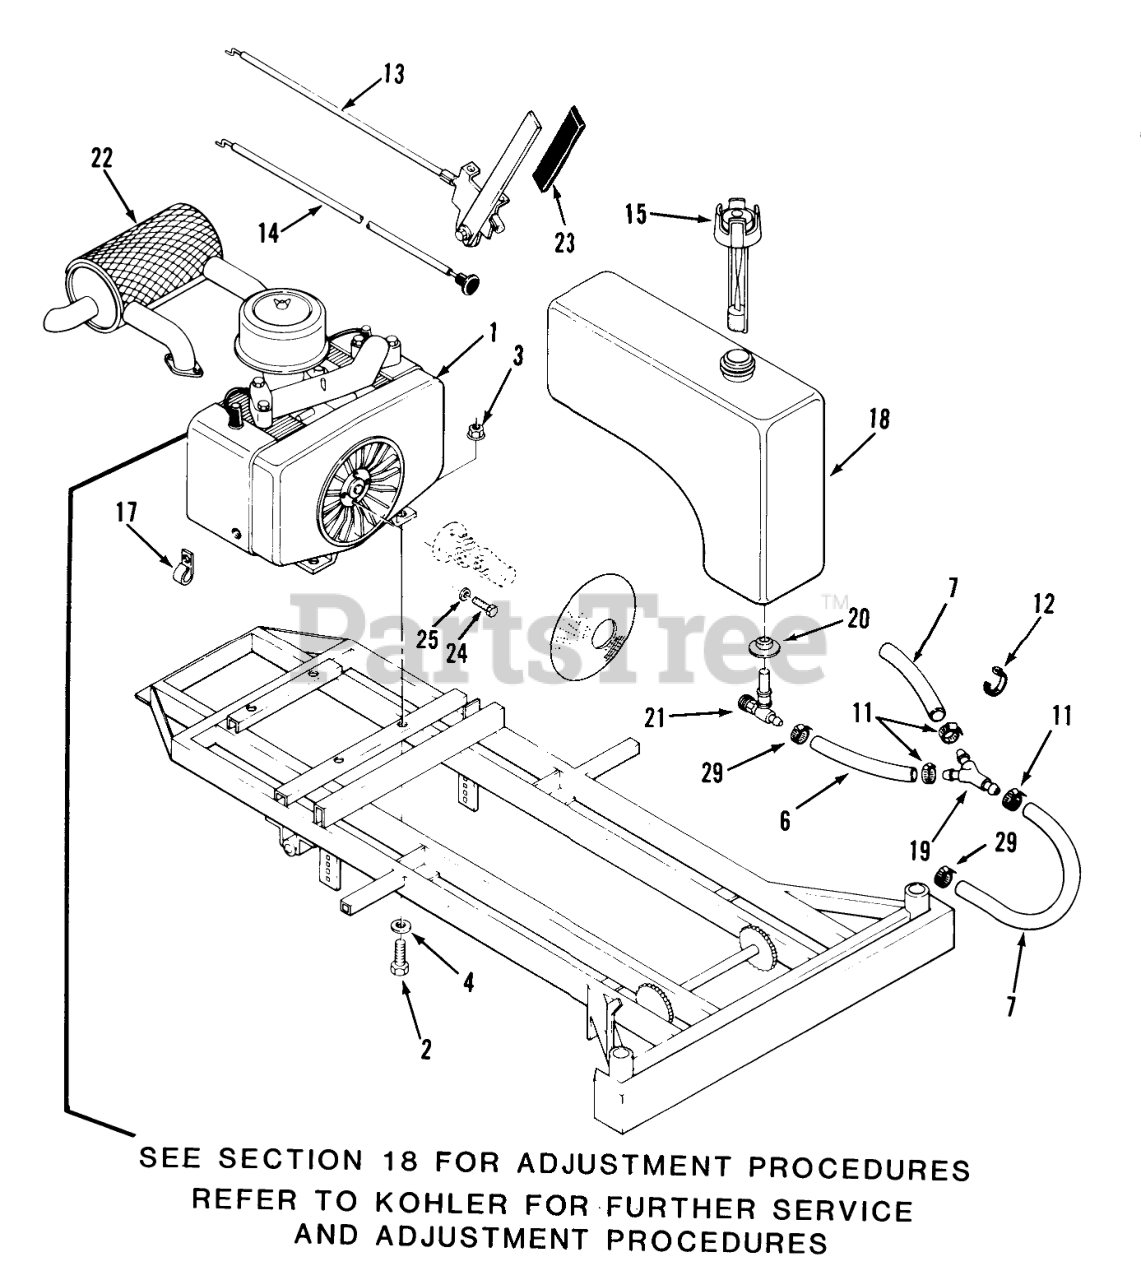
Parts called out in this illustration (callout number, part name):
1	Engine-18 HP Kohler (M18S Spec. No. 24529)
1	6802 EATON ROTARY T
2	Bolt
3	NUT
4	Washer
6	Hose5"
7	Fuel Line (32")
11	CLAMP
12	PLASTIC TIE
13	Throttle Cable (27")
14	Choke Cable (27")
15	Fuel Gauge Cap w/o screw vent
15	Fuel Gauge Cap w/screw vent
17	CLIP
18	Fuel Tank
19	FITTING-FUEL 45-Y
20	BUSHING
21	VALVE-FUEL
22	Muffler
23	GRIP BRAKE20258-K
24	BOLT
25	LOCKWASHER
29	Clamp
